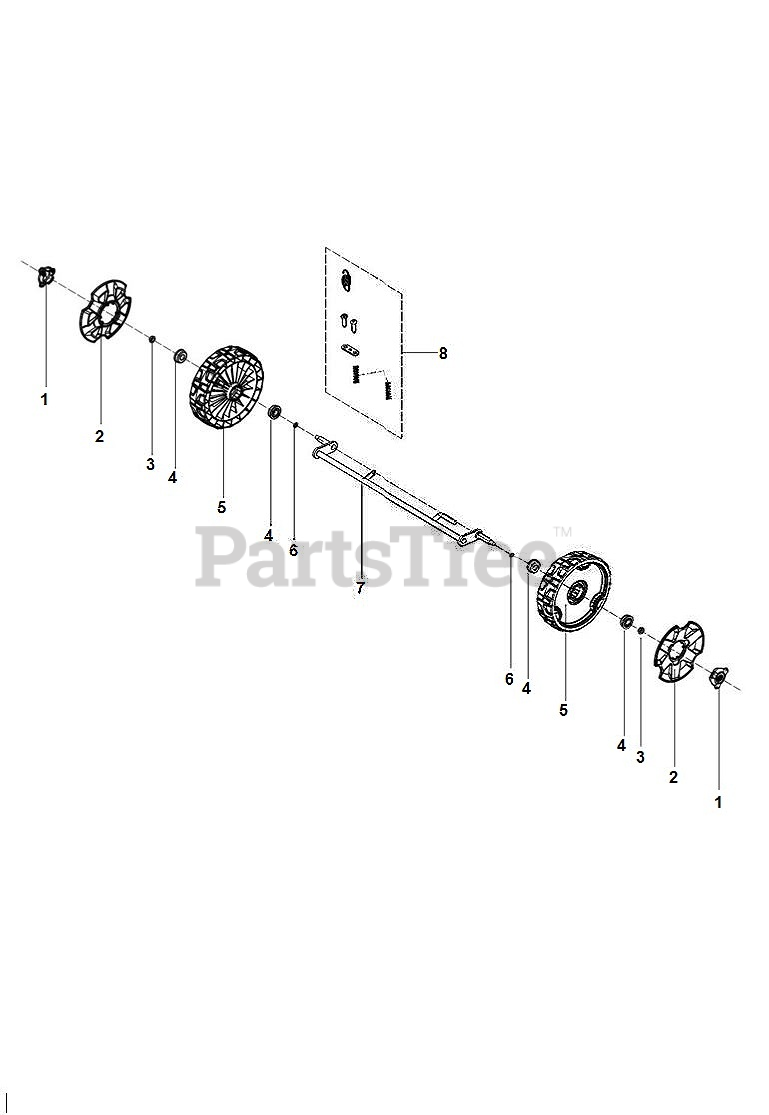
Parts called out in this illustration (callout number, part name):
1	WHEEL COVER 6" #25340700101
2	COVER 7 WHEEL COVER
3	LOCKING BOLT M8,GB6187.1 #2680
5	WHEEL ASSY 7 WHEEL
6	WASHER Ï?12 #26800706202
